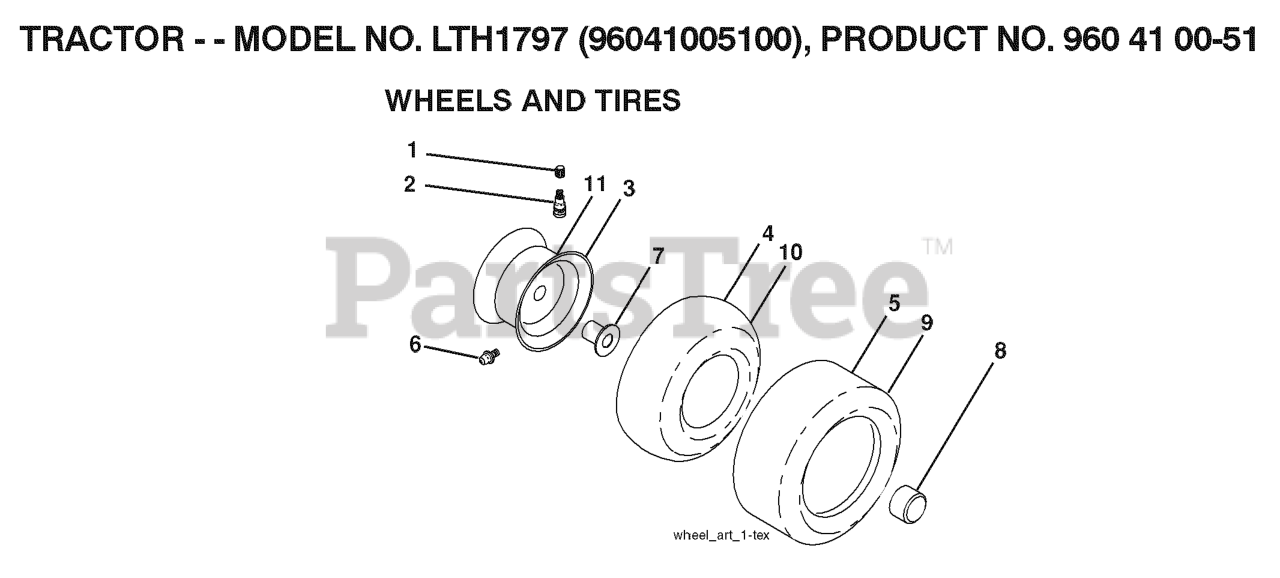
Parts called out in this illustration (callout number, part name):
2	VALVE STEM LT
3	RIM ASM 6" FRONT SILVER
4	TUBE.5.3/4.5/6
5	TIRE HEAVY DUTY
6	FITTING LT
7	BEARING T
8	CAP, AXLE BLK
9	TIRE.TS.20X10-8
10	TUBE
11	RIM ASM 8" REAR SILVER
